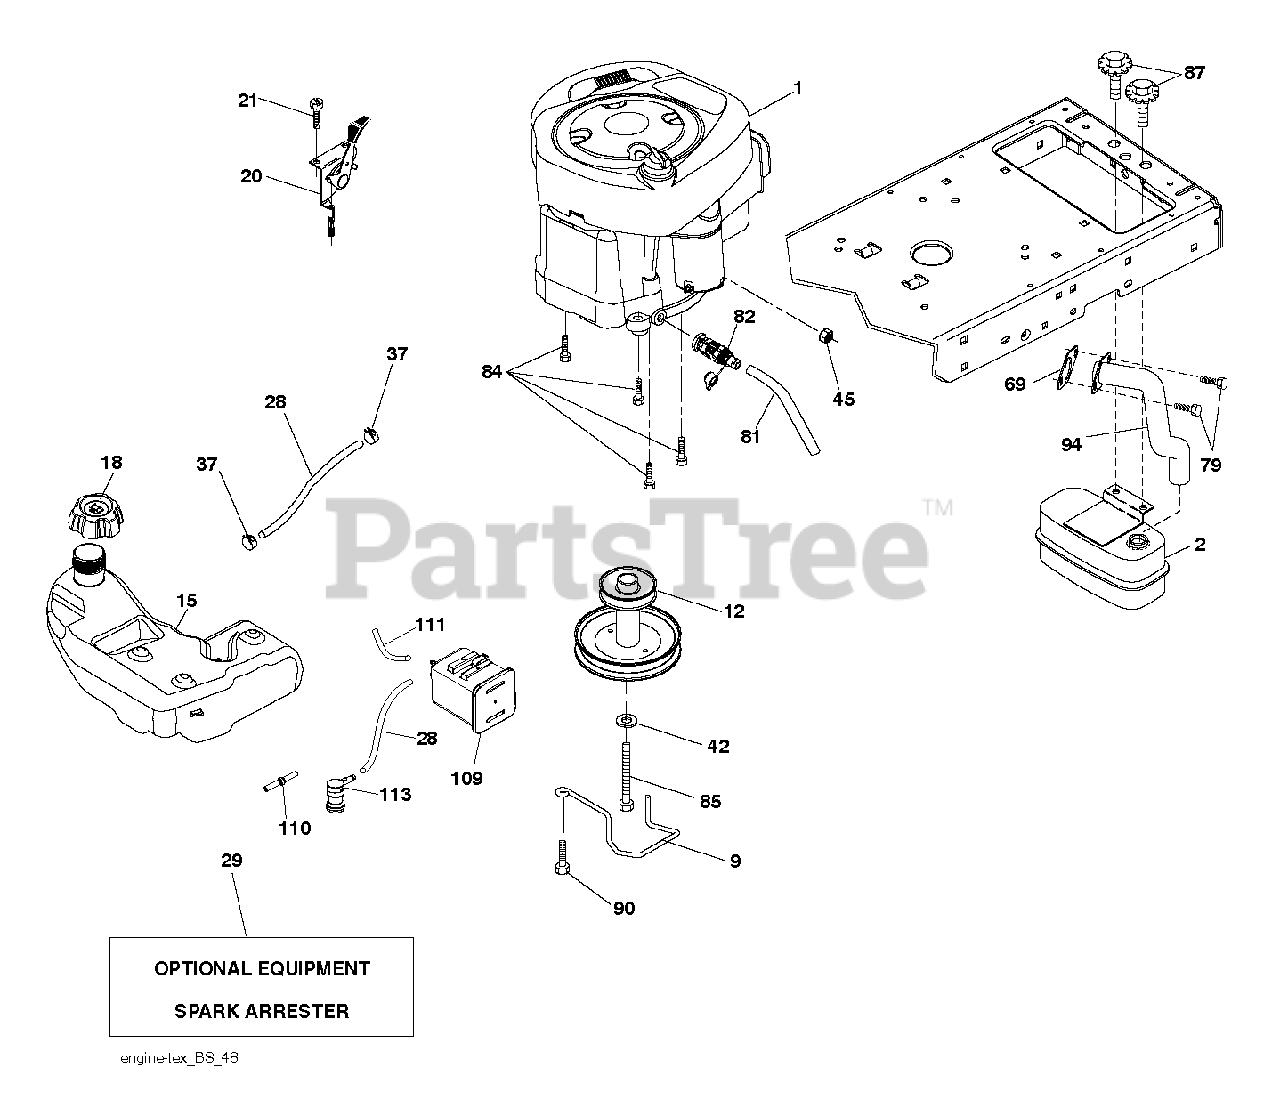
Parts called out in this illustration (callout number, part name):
2	MUFFLER.ASM.SNGL.XTNDED.DFLCTR
9	KEEPER.BELT.ENGINE
12	PULLEY.ENGINE
15	TANK.ASM.FUEL.3GA.CARB
18	CAP ASSY FUEL 3" GRAY
20	CONTROL.TH/CK.C.
21	SCREW.#10 X 0.750.BOS
28	LINE.FUEL.64"REAR.EMIS
29	KIT.SPARK ARRESTOR 794945 B&S
37	HOSE CLAMP
42	LOCKWASHER
45	NUT
69	REPL BY 532 27 22-93
79	SCREW.SOCKET HD.5/16-1
81	TUBE, DRAIN OIL ASM.
82	VALUE.OIL.DRAIN
84	SCREW.3/8-16
85	BOLT HEX 7/16-20X4-1/4"
87	BOLT, 5/16-18 X 1 3/4
90	SCREW 3/8-16X1
94	EXHAUST.TUBE.B&S.28/31
109	CANNISTER, CARBON
110	VALVE.ASM.ANTI-SLOSH
111	RP PURGE LINE
113	VALVE.SLANT.CARTRDG.90 DEG.TEX
